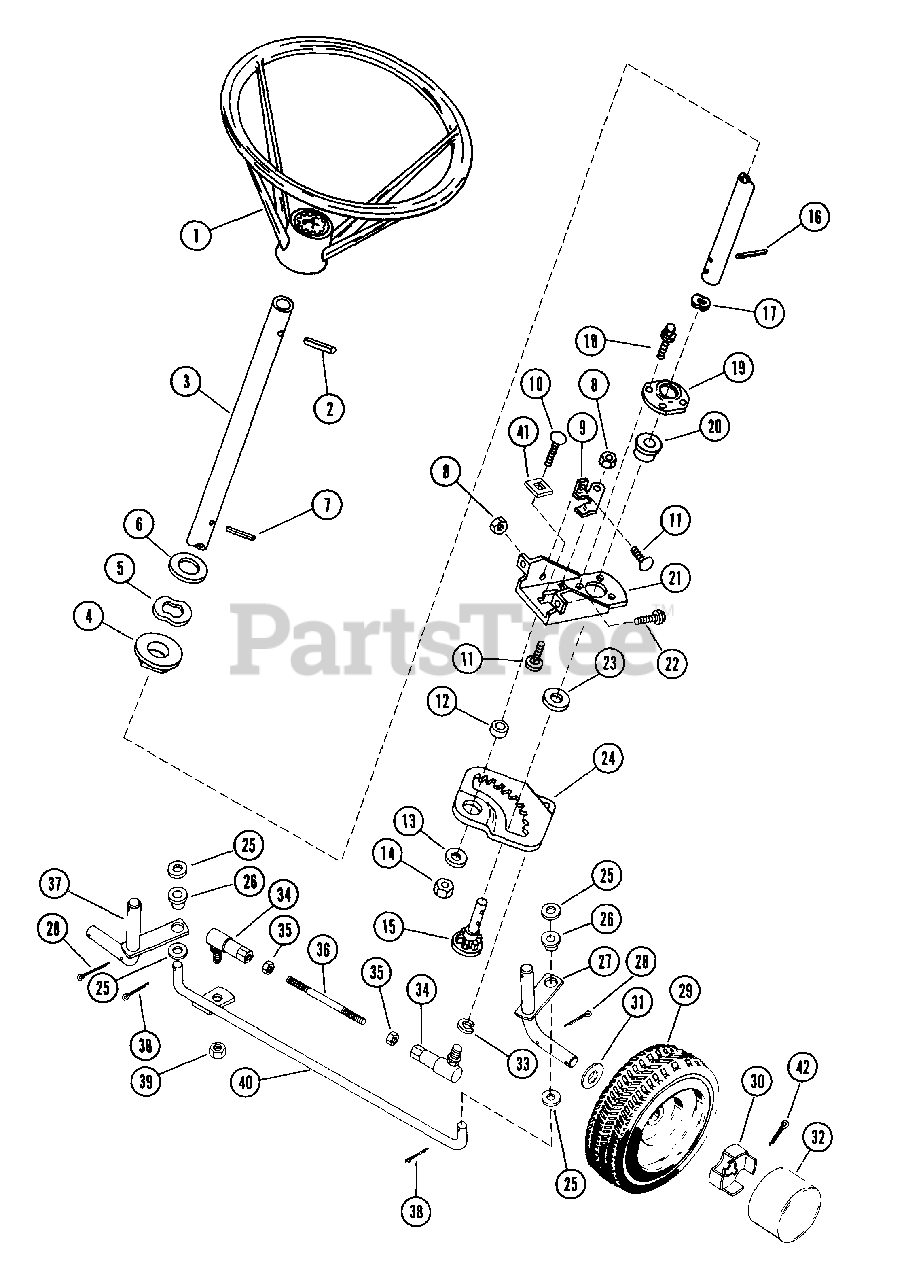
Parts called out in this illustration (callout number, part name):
1	STEERING WHEEL
2	PIN-ROLL .250X1.75
3	STEERING SHAFT
4	FLANGE BUSHING
5	SPRING WASHER
6	WSHR-FL-STL .755X1.375X.062 PL
7	PIN-ROLL .188X1.25
8	NUT-LK-CTR .250-20 PL
9	ADJUSTMENT BRACKET
10	BLT-RDHDSQSHNK .38-16X1.00 PL
11	BLT-RDHDSQNK .25-20X.62 PL
12	SPACER .380X.750X.236
13	WSHR-FL-STL .390X1.500X.125
14	NUT-LK-CTR .375-16 GR A PL
15	STEERING PINION
16	PIN-ROLL .188X1.00
17	WAVE WASHER .531X.781X.125FH
18	SCR-TAP 10-24X.25 CRSLPH PL 1A
19	RETAINING PLATE
20	BSHG-FLG .625X1.156X.375 SI
21	STEERING BRACKET
22	BLT-SERHFWH .31-18X.50 PL
23	WSHR-FL-STL .630X1.005X.062 PL
24	STEERING GEAR
25	WSHR-FL-STL .505X.875X.024 PL
26	BSHG-FLG.500X.625X.312X.750NY
27	L H WHEEL SPINDLE
28	PIN-COTR .12 X 1.25 PL
29	FRONT WHEEL ASSEMBLY
29	TIRE 4.10/3.50-4
29	WHL
29	ZERK FITTING
29	BSHG-FLG .750X1.380X.750X1.557
29	BRG-BALL .752X1.50X.50
30	SPINDLE CUP
31	SPINDLE WASHER
32	HUB CAP
33	WSHR-LK .375X.115 HVY PL
34	BALL JOINT
35	NUT .375-24 PL
36	STEERING LINK
37	R H WHEEL SPINDLE
38	PIN-COTR .12X1.0 PL
39	NUT-LK-CTR .375-24
40	TIE ROD
41	WASHER
42	PIN-COTR .12X1.0 PL
